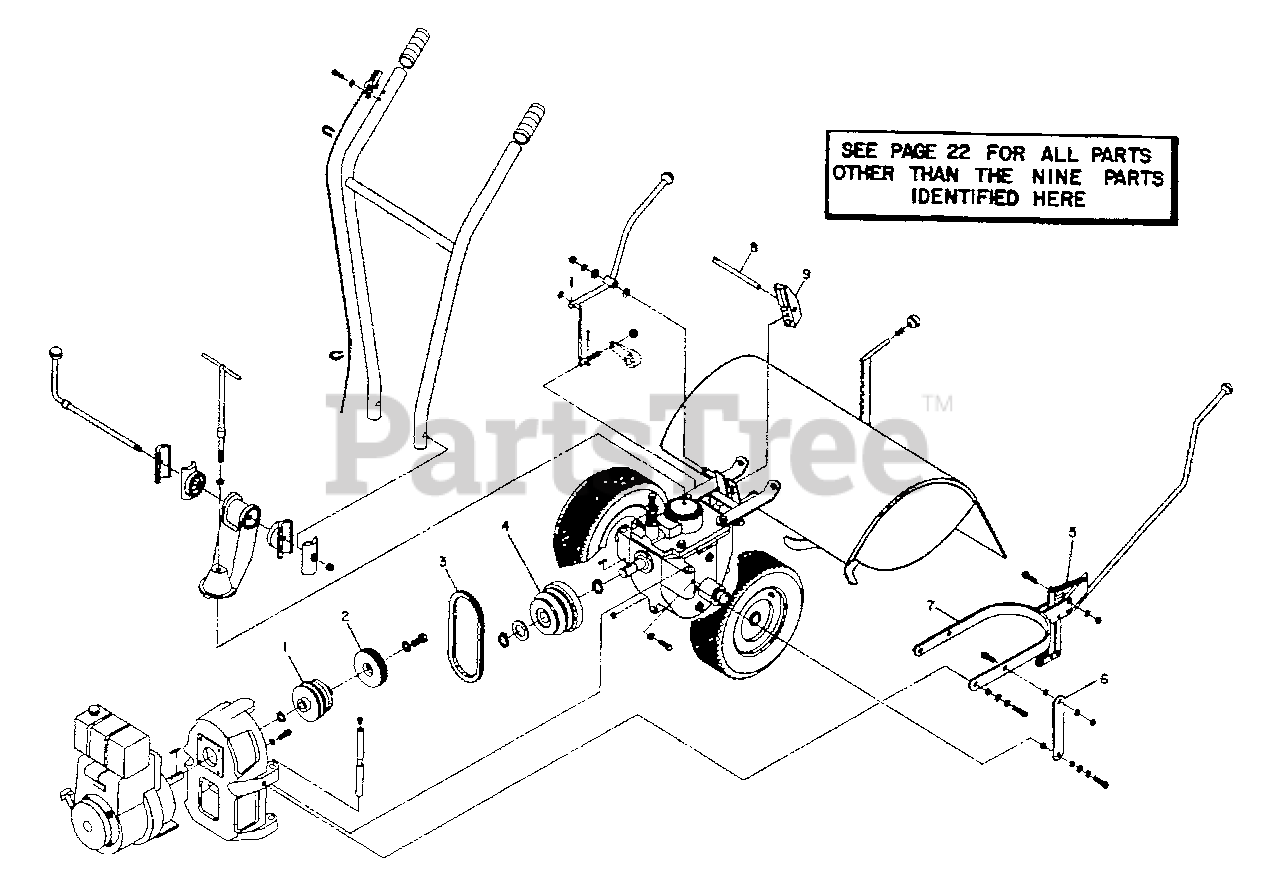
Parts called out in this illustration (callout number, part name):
1	PULLEY-ENG MACH
2	KIT-ADJ BLOCK/REV DISC
4	PULLEY-TRANS-MACH
5	SPRING-.436 X 3.25
6	BAR-CLUTCH YOKE
7	KIT-LEVER FWD/REV-HORSE 2
8	BAR-ADJUST
9	KIT-ADJ BLOCK 4 SP
